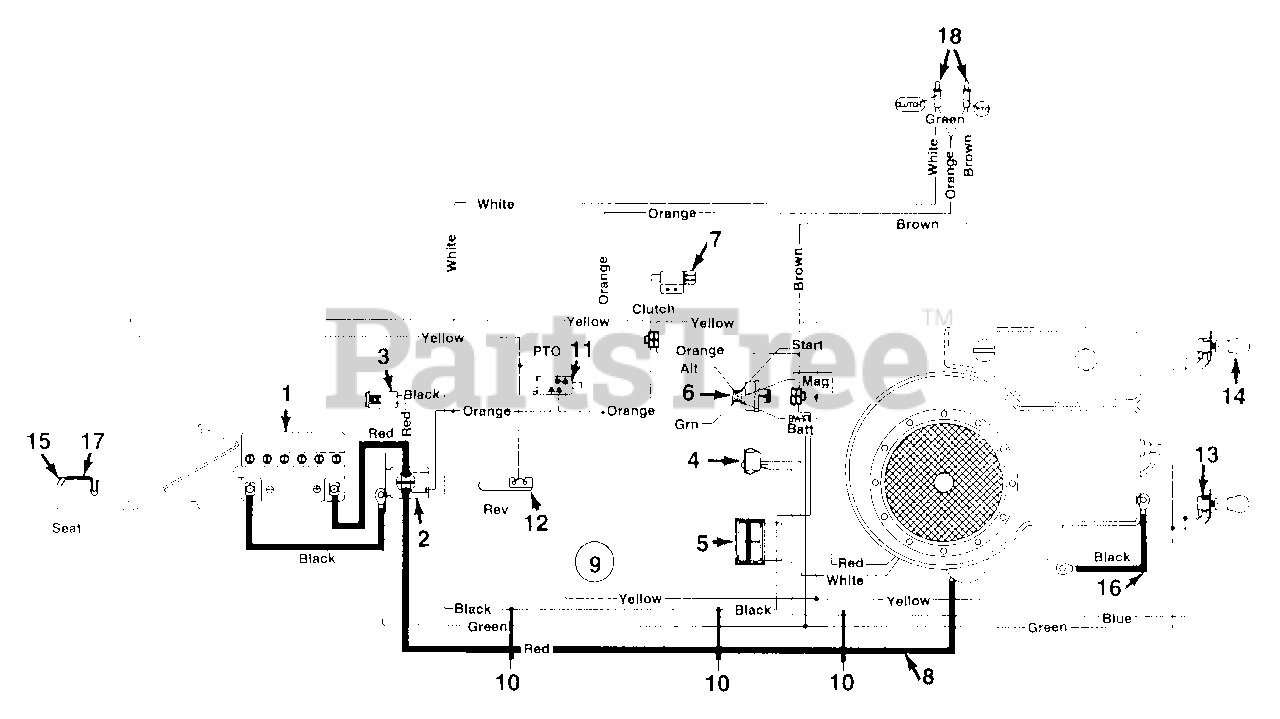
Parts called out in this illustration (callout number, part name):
1	Battery
2	Solenoid
3	Fuse 7.5 Amps
4	Light Switch
5	Ammeter
6	Ignition Switch
7	Safety Switch
8	Electric Wire 30" Lg.
9	Wire Harness
11	Safety Switch (Deck)
12	Safety Switch (Reverse)
13	Socket
14	Bulb (Headlight)
15	Safety Switch (Seat)
16	Ground Wire 7.5" Lg.
17	Safety Switch (Seat)
18	Bulb
